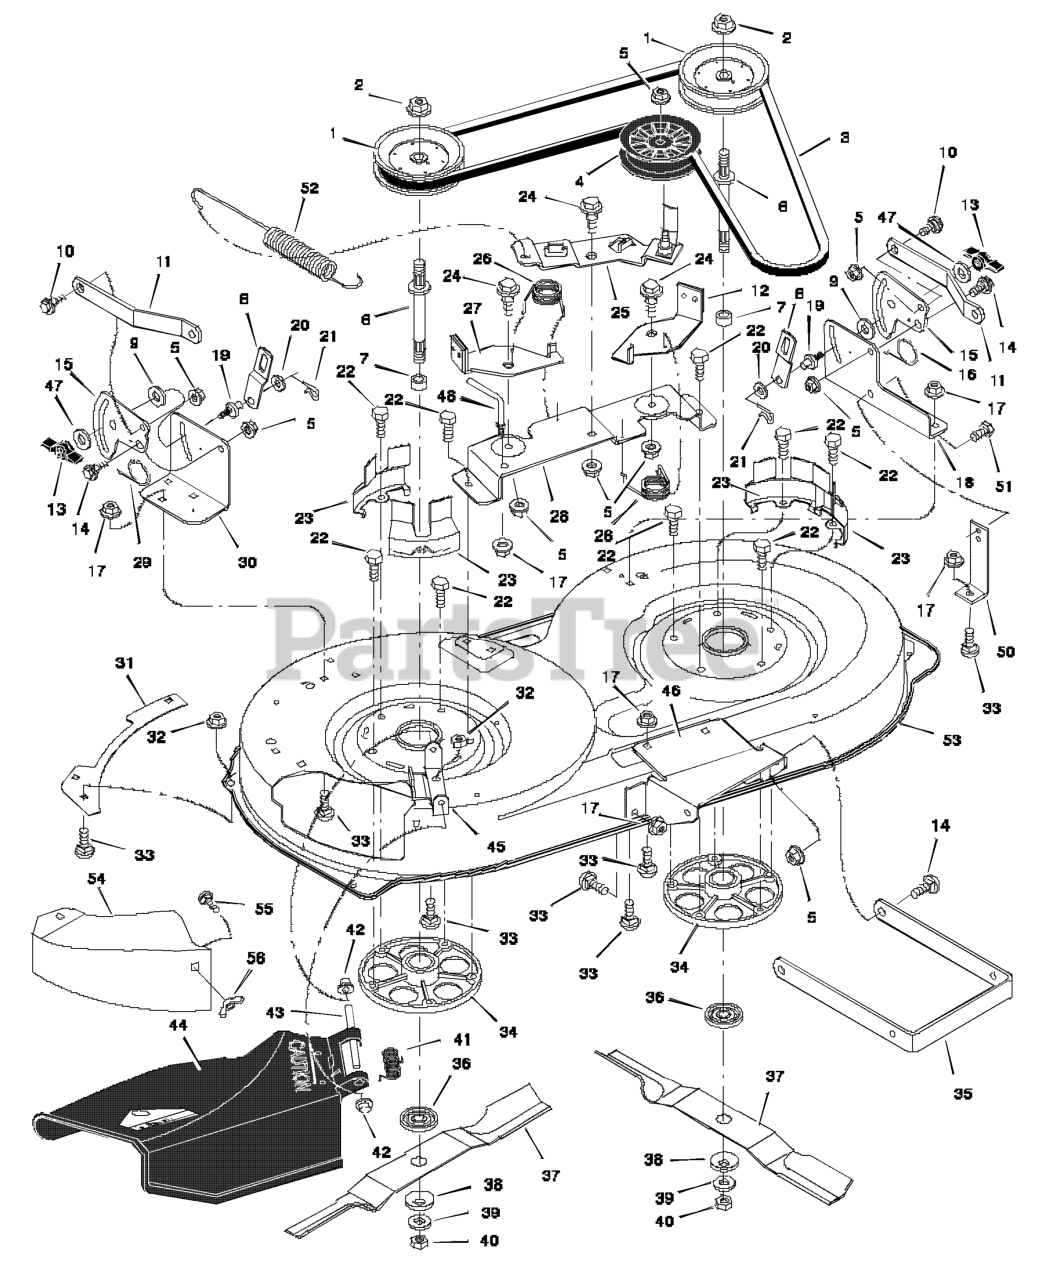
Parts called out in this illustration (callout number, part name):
1	Pulley, Jackshaft
2	Nut, Hex
3	Belt, Mower Drive
4	Pulley, Idler
5	Nut, Flange
6	Jackshaft
8	Link, Lift
9	Pad, Friction
10	Bolt, Shoulder
11	Bracket, Suspension
12	Pad Assembly, Left Brake
13	Knob
14	Bolt, Shoulder
15	Plate, Suspension
17	Nut, Flange
18	Bracket, Suspension
19	Pin, Hanger
21	Pin, Cotter
22	Bolt
23	Cover, Pulley
24	Bolt, Shoulder
25	Arm, Idler
27	Pad Assembly, Right Brake
28	Bracket Assembly, Brake
30	Bracket, Suspension
31	Plate
32	Nut, Flange
33	Bolt, Carriage
34	Mandrell
35	Bracket, Suspension
36	Adapter, Blade
37	Blade, 40" (Left)
42	Cap, Push On
43	Rod, Pivot
44	Deflector
45	Bracket, Deflector
46	Bracket, Front Hanger
48	Guide, Belt
50	Bracket, Support
52	Spring, Extension
53	Housing, Blade
54	Cover, Mulcher
55	Bolt, Carriage
56	Wingnut
